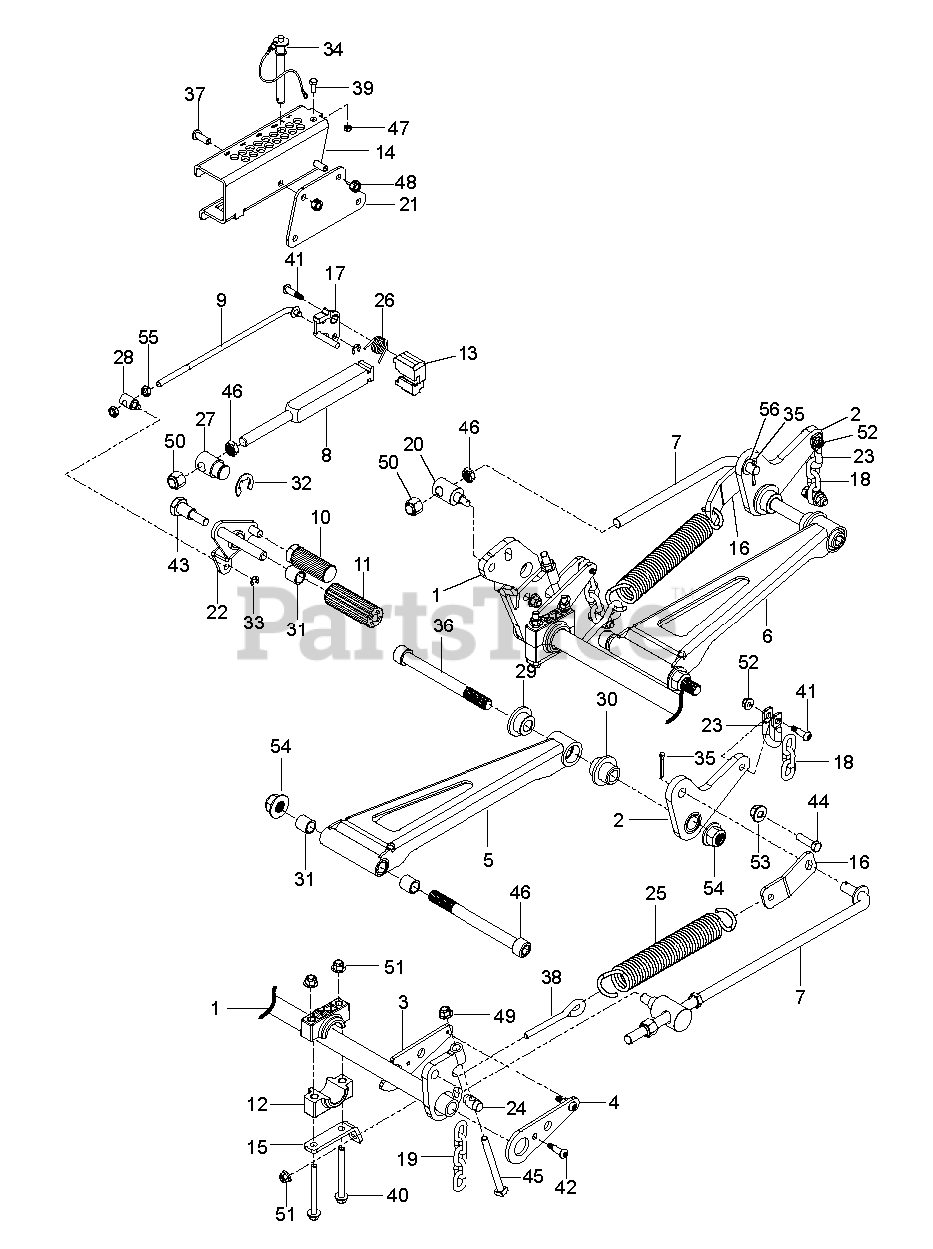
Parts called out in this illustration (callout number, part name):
1	SHAFT.WLDMNT.FRNT.DECK.LFT.PNT
2	KIT.ARM.BELLCRANK/BUSHINGS.RT
2	KIT.ARM.BELLCRANK/BUSHINGS.LT
3	ARM.DECK.LIFT.INNER.BLACK
4	ARM.LIFT.DECK.OUTER.POWER.BLK
5	ARM.DRAWBAR.LH
6	ARM.DRAWBAR.RH
7	ROD. CONNECTING
8	ROD.HEIGHT.GAUGE
9	ROD.RELEASE.CONNECTING.TOE
10	PEDAL, DECK HEIGHT
11	PAD, FOOT PEDAL
12	BLOCK, PILLOW
13	BLOCK.ROD.END
14	BRACKET.ADJUSTMENT.HEIGHT.ORNG
15	BRACKET.PILLOW.BLOCK.PNT.BLACK
16	BRACKET SPRING BLACK (X428)
17	KIT.LEVER.LOCK.W/BUSHING
18	LIFT CHAIN - 3 LINK
19	LIFT CHAIN
20	PIVOT.CONNECTING.ROD
21	PLATE.HEIGHT.GAUGE.MOUNT.PNT
22	LEVER ASSY TOE RELEASE
23	SHACKLE.CHAIN
24	SHAFT.TRUNNION.ATTACH
25	SPRING EXTENSION, DECK LIFT, H
26	SPRING.TORSION.RELEASE.LEVER
27	SWIVEL.HEIGHT.BAR
28	SWIVEL.TOP.RELEASE
29	BUSHING.DECK.INNER
30	BUSHING.DECK.OUTER
31	BUSHING, SLEEVE 3/4 X 1.0
32	E-RING 1"
33	E RING 3/8"
34	PIN.PUSH.BUTTON.DETENT..5X3.5
35	COTTER PIN 1/8 X 2
36	SCREW.SOCKET.HEADCP.3/4-10X7.5
37	SCREW.BUTTON.HEAD.CAP.3/8-16X1
38	EYE BOLT, 3/8 X 4"
39	HCS 1/4C X 3/4 HCS
40	SCREW.HHFS3/8-16X3.75.GR8
41	SCREW.SHOULDER.375X875.5/16-18
42	SCREW.SHLDR..375.5/16-18.88.LG
43	BOLT, SHOULDER
44	HCS 7/16C X 1 1/2
45	SCREW.HHC.7/16-14 X 4.50
46	NUT.HH.THIN.NYL.5/8-11 GR5
47	NUT.1/4-20.HEX.NYLOC.ZD
48	NUT 3/8C CENTERBLOCK
49	NUT FLANGE, NYL 7/16-14
50	NUT 5/8-11 NYLOC
51	NUT 3/8-16 HEX FLG NYLOC ZD
52	5/16-18 NYLOC FLANGE NUT
53	NUT 7/16-14 HEX WHIZ LK
54	NUT.HEX.FLANGED.3/4-10.NYLOK
55	NUT 3/8-24 JAM
